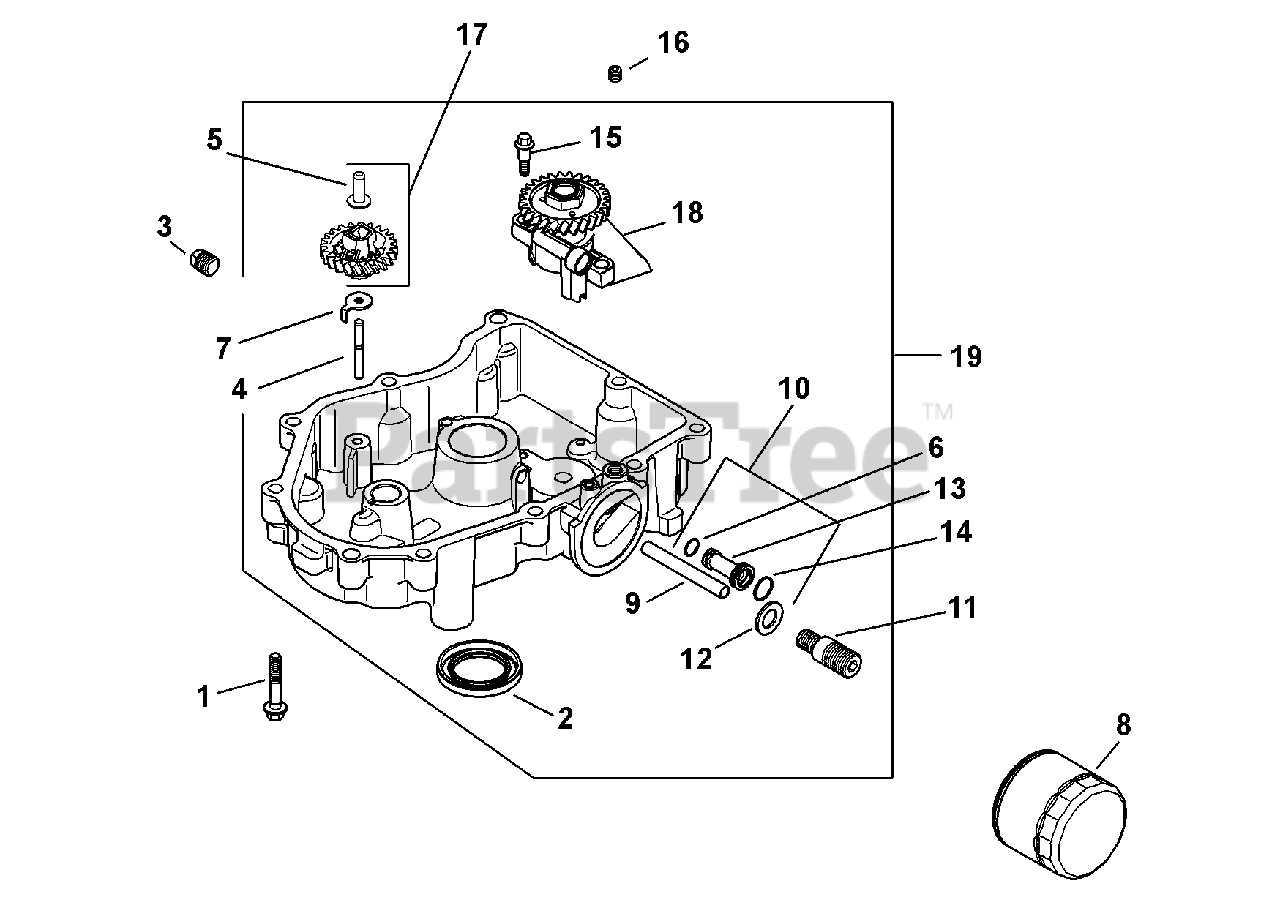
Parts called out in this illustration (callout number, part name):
1	Flg. Screw, M8 x 1.25 x 45
3	Sq. Hd. PipePlug, 3/8
4	Governor Gear Shaft
5	Governor Regulating Pin
6	Oil Pick-Up O-Ring
9	Oil Feed Tube - Filter To Pan
10	Oil Feed Tube Assembly
11	Oil Filter Nipple
13	Oil Feed Tube
15	Shd. Thd. Frm. Screw, M6 x .0 x 6.5
16	Pipe Plug, 1/8"
17	Governor Gear Kit (Inc. 5)
18	Oil Pump Assembly
19	Oil Pan Assembly
